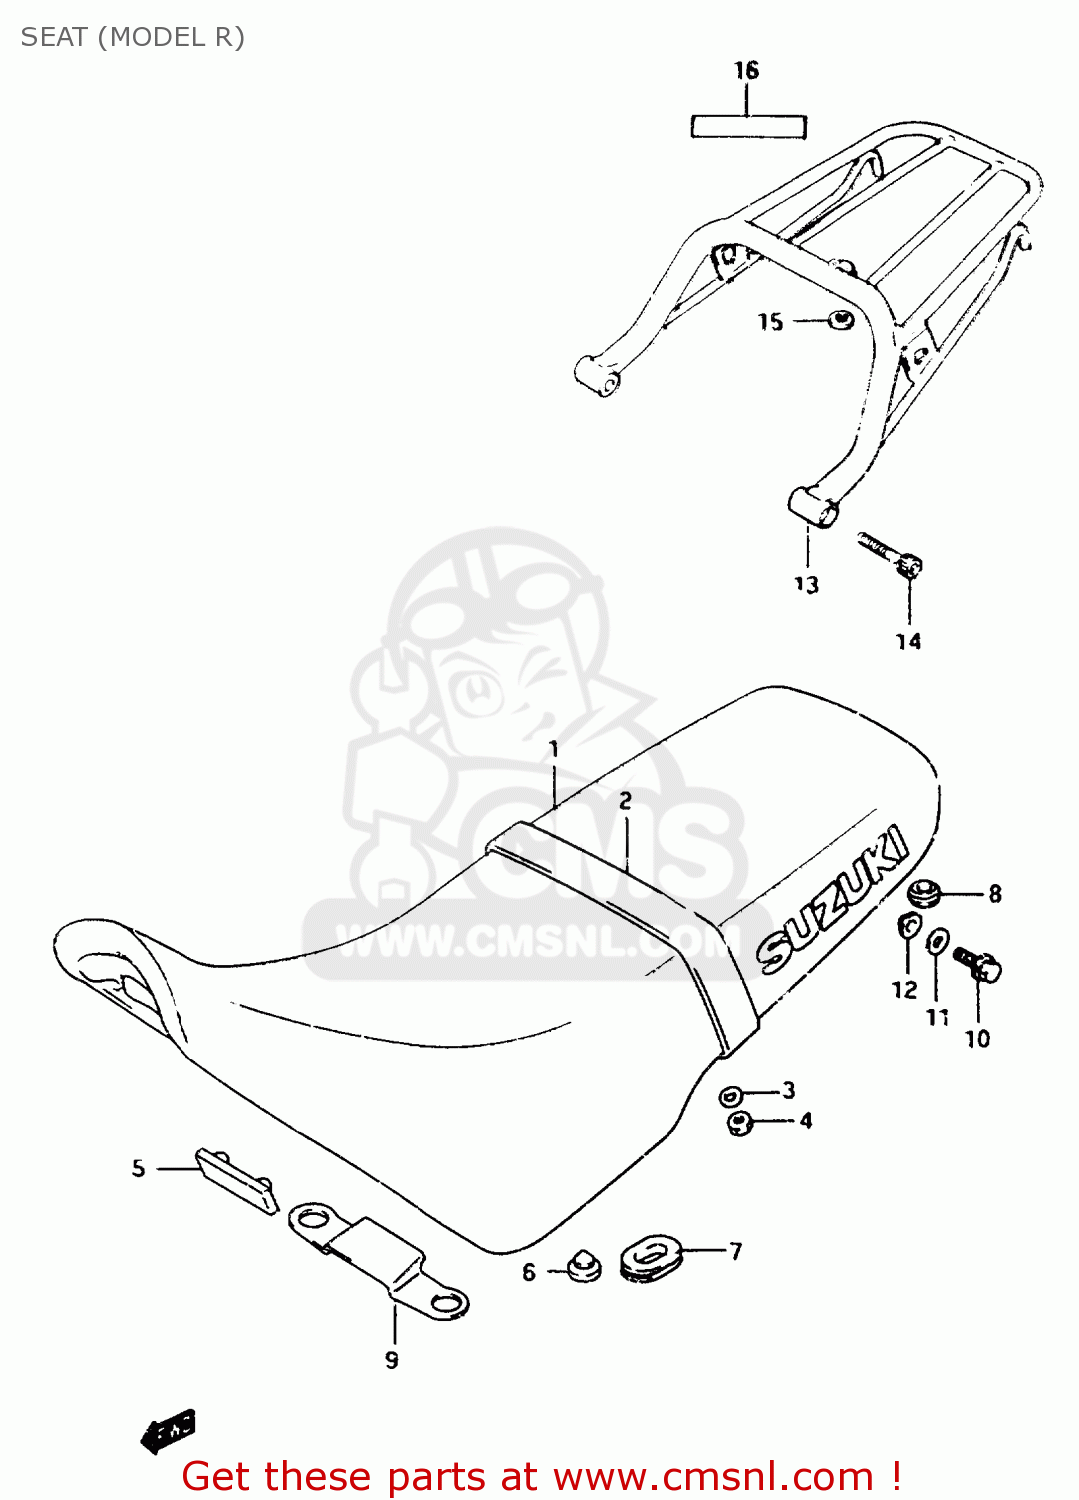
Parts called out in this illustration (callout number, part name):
1	SEAT SET
2	BAND,SEAT
3	WASHER(6.5X18X1.6)
4	NUT
5	CUSHION
6	CUSHION
7	CUSHION
8	CUSHION
9	PLATE,SEAT FR HOOK
10	BOLT
11	WASHER (8.7X22X2)
12	WASHER
13	CARRIER SET,SPORT
14	BOLT
15	WASHER (8.5X18X3.2)
16	LABEL (WARNING)
